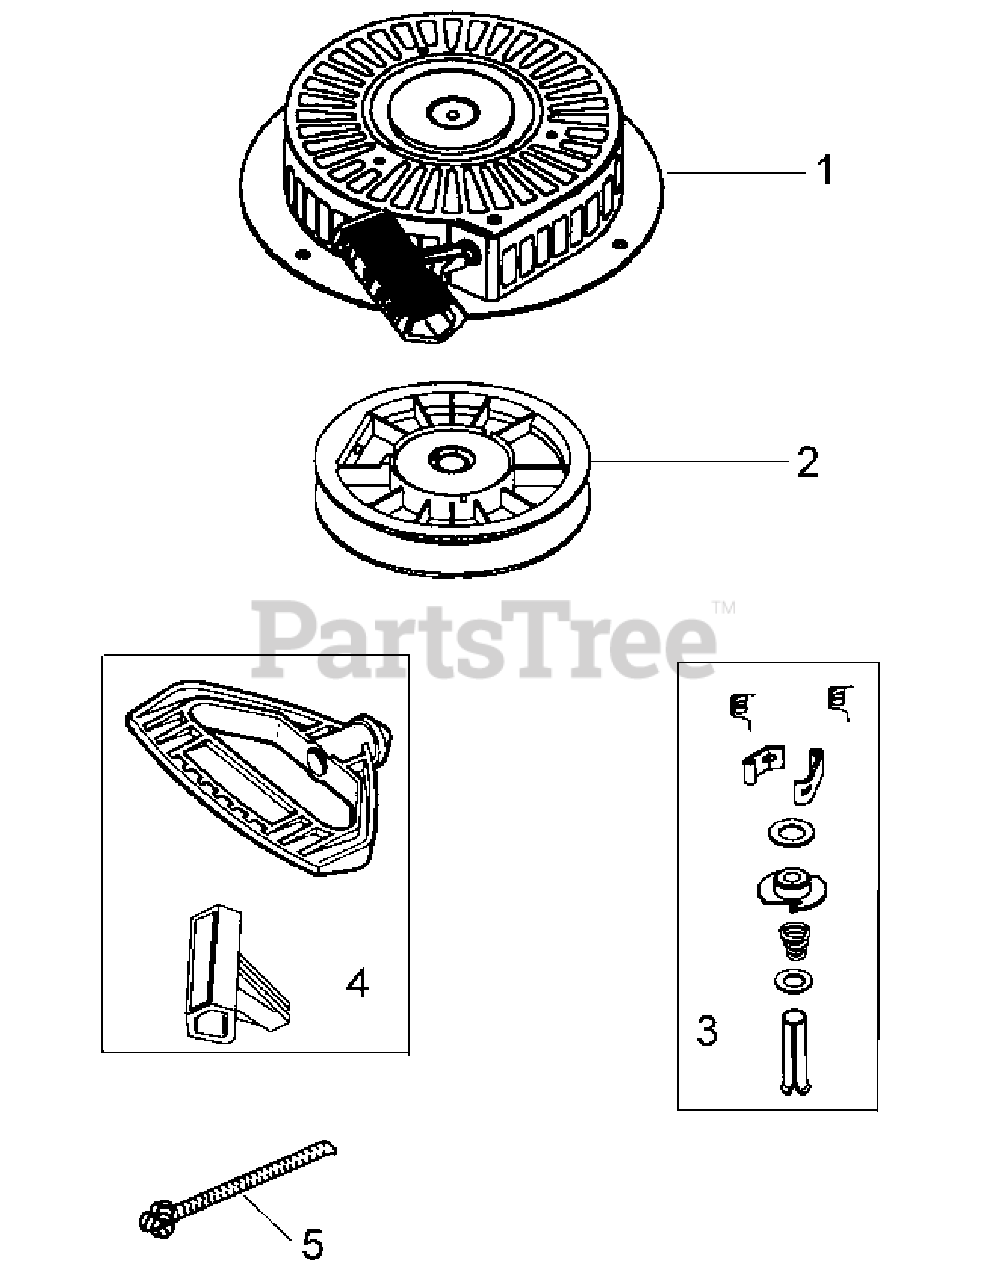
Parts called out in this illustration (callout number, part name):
1	Rewind Starter
2	Pulley & Rewind Spring Assembly
3	Repair Kit
4	Starter Handle
5	98" Starter Rope (cut to length)
